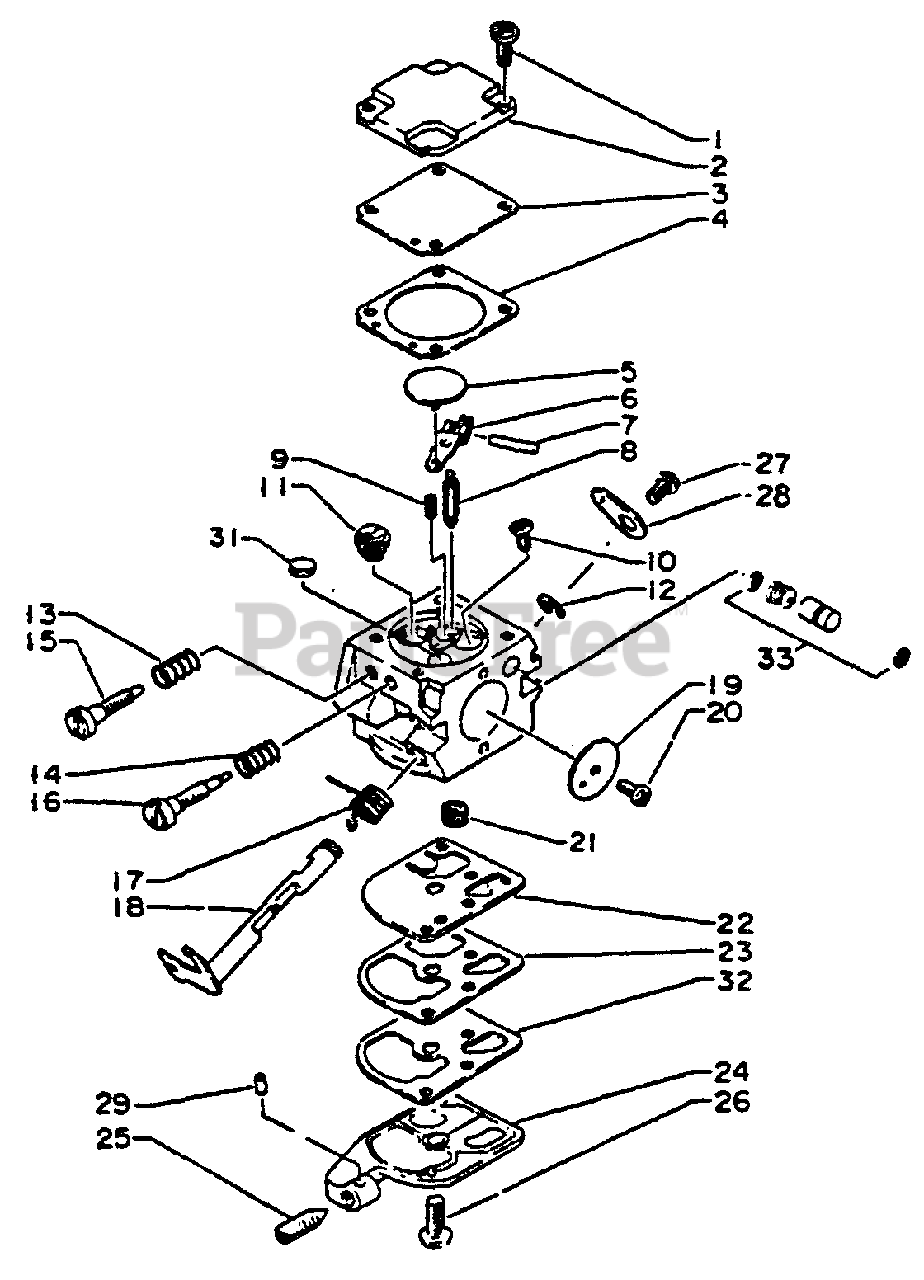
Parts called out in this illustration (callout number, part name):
2	COVER, METERING
3	DIAPHRAGM
4	GASKET, METERING
5	PLUG, WELCH
6	LEVER, METERING
7	PIN, METERING LEVER
8	NEEDLE, INLET
9	SPRING, METERING LEVER
10	SCREW, METERING LEVER PIN
11	ORIFICE, MAIN FUEL
12	RING, RETAINING
13	SPRING
15	NEEDLE - HIGH SPEED
16	NEEDLE - LOW SPEED
17	SPRING, RETURN
18	SHAFT, THROTTLE
19	VALVE, THROTTLE
20	SCREW
21	STRAINER
22	DIAPHRAGM, PURGE
23	GASKET, PURGE
24	BASE, PUMP
25	SCREW, IDLE ADJUST
26	SCREW, PUMP COVER
28	LEVER, THROTTLE
29	PIECE, FRICTION
31	PLUG, WELCH
32	DIAPHRAGM, SURGE
33	PUMP KIT
